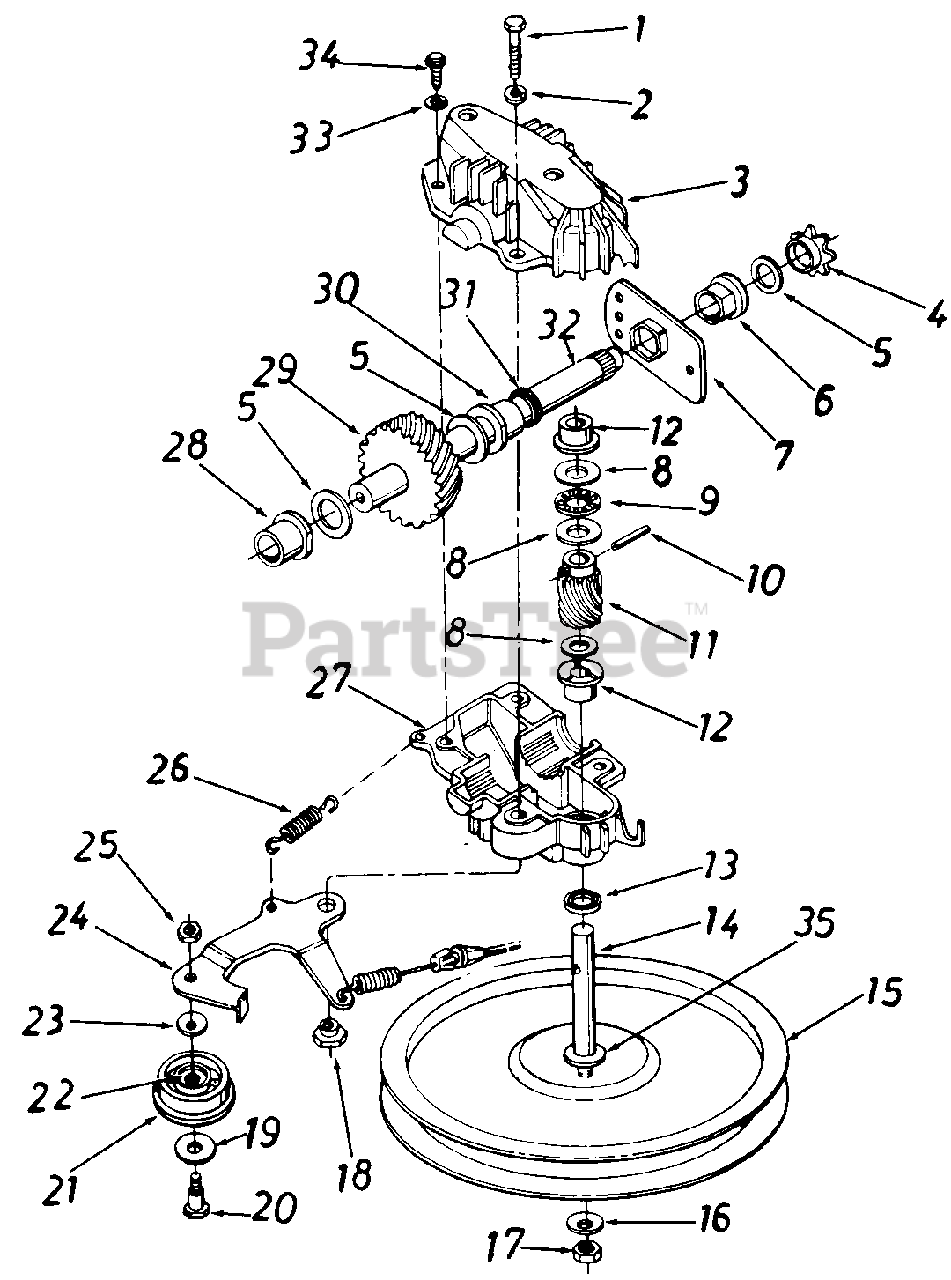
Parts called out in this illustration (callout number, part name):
1	Hex Bolt 1/4-20 x 1.25" Lg.
2	L-Wash. 1/4" I.D.
3	Upper Hsg. Half
4	#48 Sprocket 7 Tooth x 1/2 0 Pitch
5	Fl-Wash. 5/8" I.D. x .030
6	Hex Flange Brg. .631" I.D.
8	Thrust Wash. .382" I.D. x .70" O.D.
9	Thrust Bearing .375" I.D. x .812" O.D.
10	Spring Pin Spir. 1/8" x .62" Heavy
11	11 Tooth Helical Gear
12	Flange Bearing
14	Pulley-Transmission Shaft
15	Fl-Pulley 5.06" O.D.
16	Bell-Wash. .265" I.D. x 75"
17	Hex L-Nut 1/4-28 L.H. Thd.
18	Shld. Spacer .375" Dia. x .170
19	Fl-Wash. .390" I.D. x 1.0"
20	Shld. Bolt .375" Dia. x .40"
21	Fl-ldler Plastic 1.50" Dia.
22	Needle Brg. .375" x .31
23	Bell-Wash. .265" I.D. x 75"
24	Idler Brkt. Ass y.
25	Hex Patch L-Nut 1/4-28 Thd
26	Extension Spring 1.12" Lg.
27	Lower Hsg. Half
28	Flange Bearing .566 Dia.
29	33 Tooth Helical Gear
30	Flange Bearing .629 Dia.
31	Oil Seal .625 Dia.
32	Gear Sprocket Shaft
33	L-Wash. #10 I.D.
34	Hex B-Tap Scr. #10 x .62"
35	Hex Washer .26" x .88"
